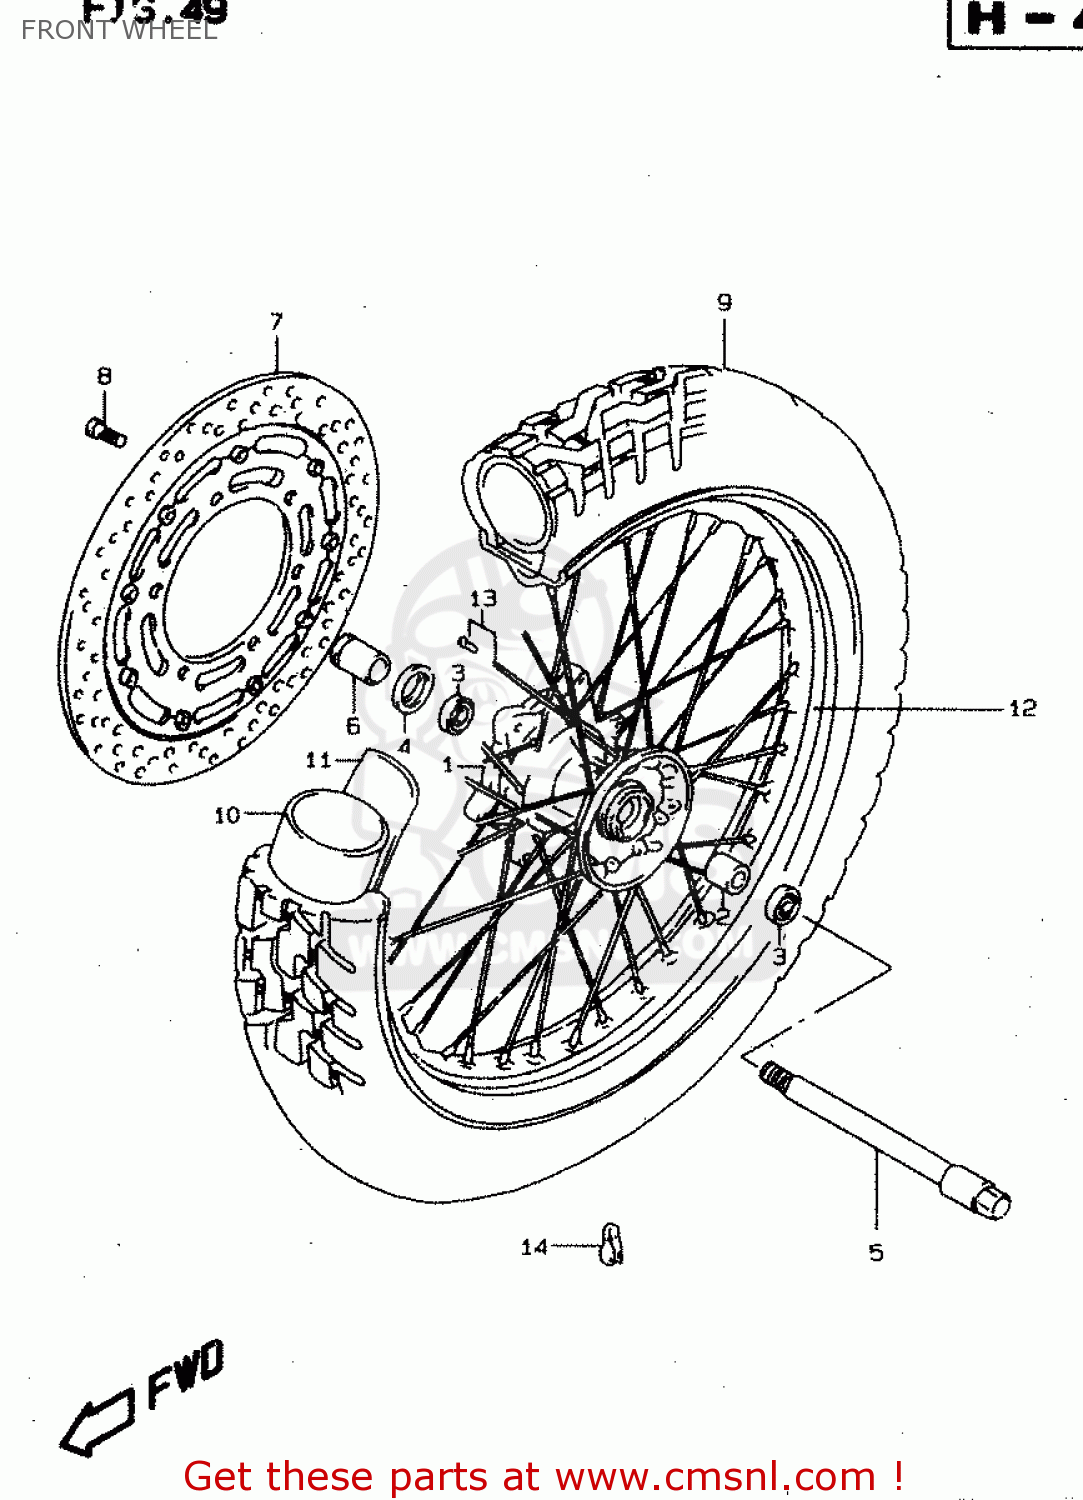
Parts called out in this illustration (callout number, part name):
1	HUB,FR WHEEL
2	SPACER,FR HUB BEARING
3	BEARING
4	SEAL,OIL(23X35X6)
5	AXLE,FR
6	SPACER,FR AXLE,L
7	DISC,FR BRAKE
8	BOLT,BRAKE DISC
9	TIRE, FRONT (PIRELLI) (100/90-19 57H MT8
10	TUBE ASSY, WHEEL INNER (PIRELLI)
11	PROTECTOR, INNER TUBE (PIRELLI)
12	RIM,FR.WHEEL
13	SPOKE SET,FR WHEEL
14	BALANCER,WHEEL
